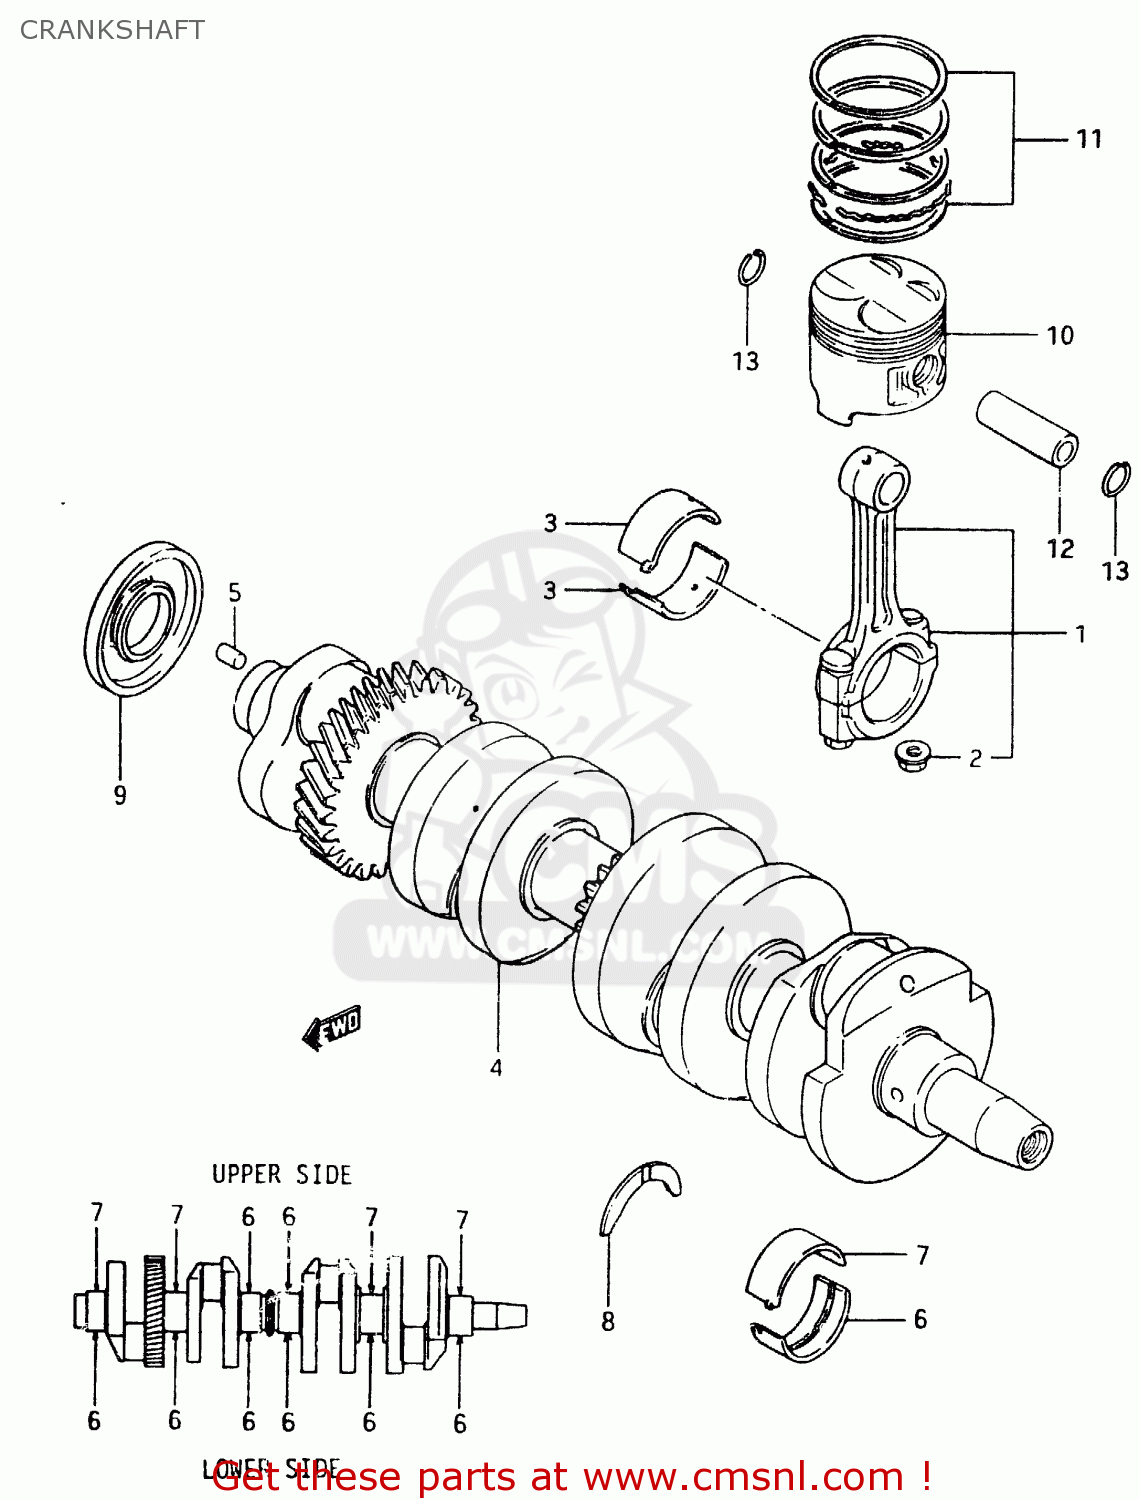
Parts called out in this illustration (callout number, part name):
1	ROD ASSY, CONNECTING
2	NUT
3	BEARING,CRANK PIN
4	CRANKSHAFT
5	PIN
6	BEARING,CRANKSHAFT
7	METAL CRANKSHAFT
8	PLATE,CRANK THRUST
9	OIL SEAL 30X56
10	PISTON
11	RING SET,PISTON(STD)
12	PIN,PISTON
13	RING,SNAP 14MM
